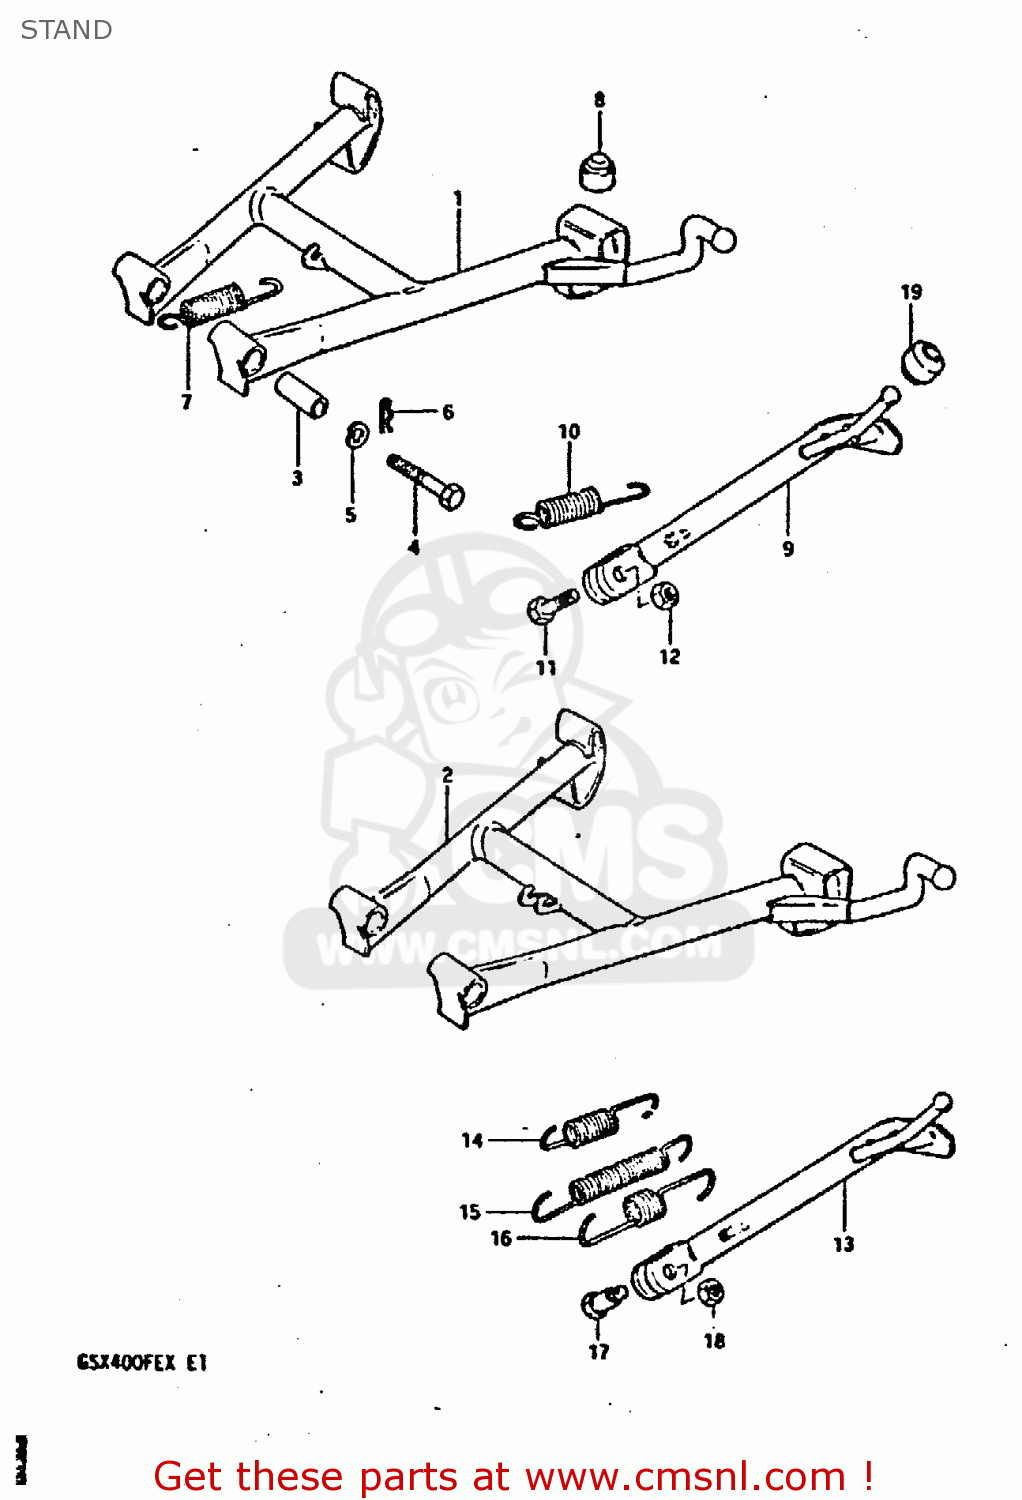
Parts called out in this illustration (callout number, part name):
1	STAND, CENTER
3	SPACER(10X16X38.8)
4	BOLT
5	LOCK WASHER
6	CLIP
7	SPRING
8	CUSHION
9	STAND, PROP
10	SPRING
11	BOLT(10X30)
12	NUT
19	CUSHION
